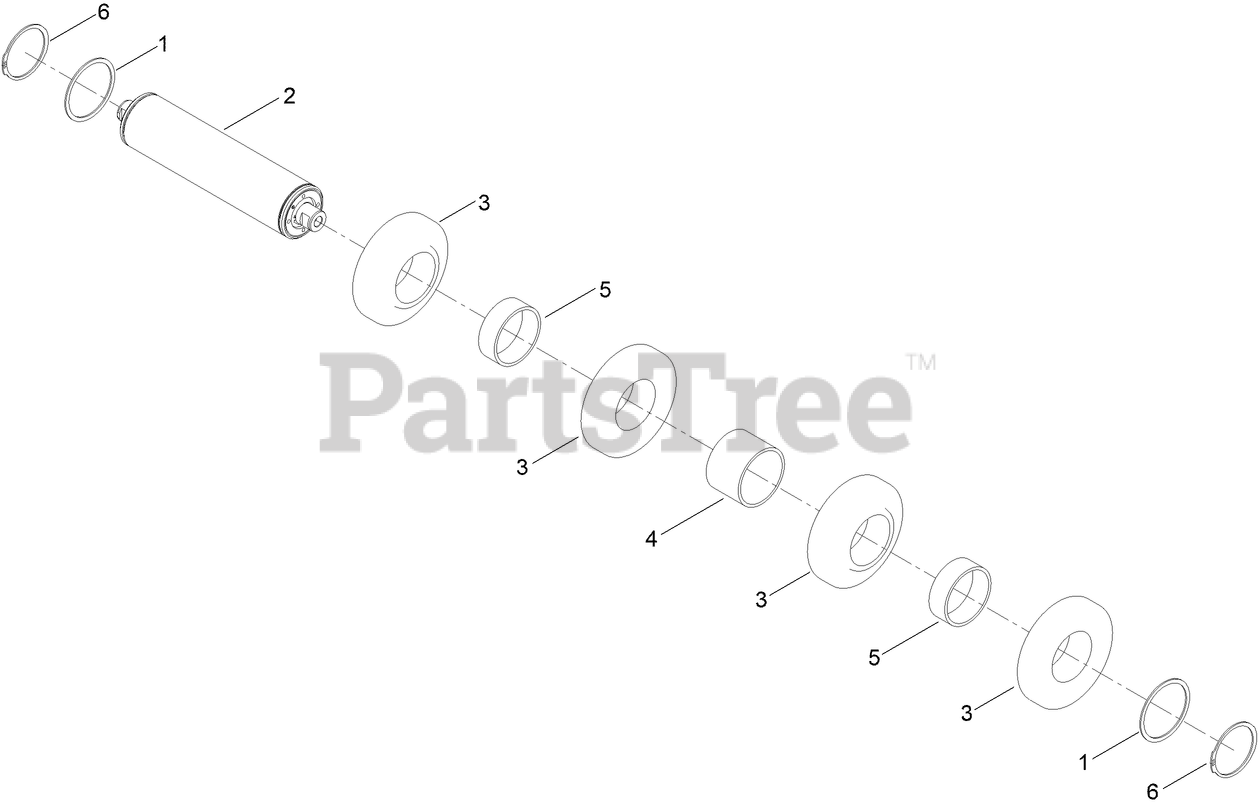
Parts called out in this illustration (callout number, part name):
1	RING-RETAING, TRACK WHEEL
2	AXLE ASS'Y
3	WHEEL-MOLDED, TRACKS, 8IN
4	SPACER-WHEEL
5	SPACER-WHEEL
6	RING-RETAINING,EXTERNAL 4IN
